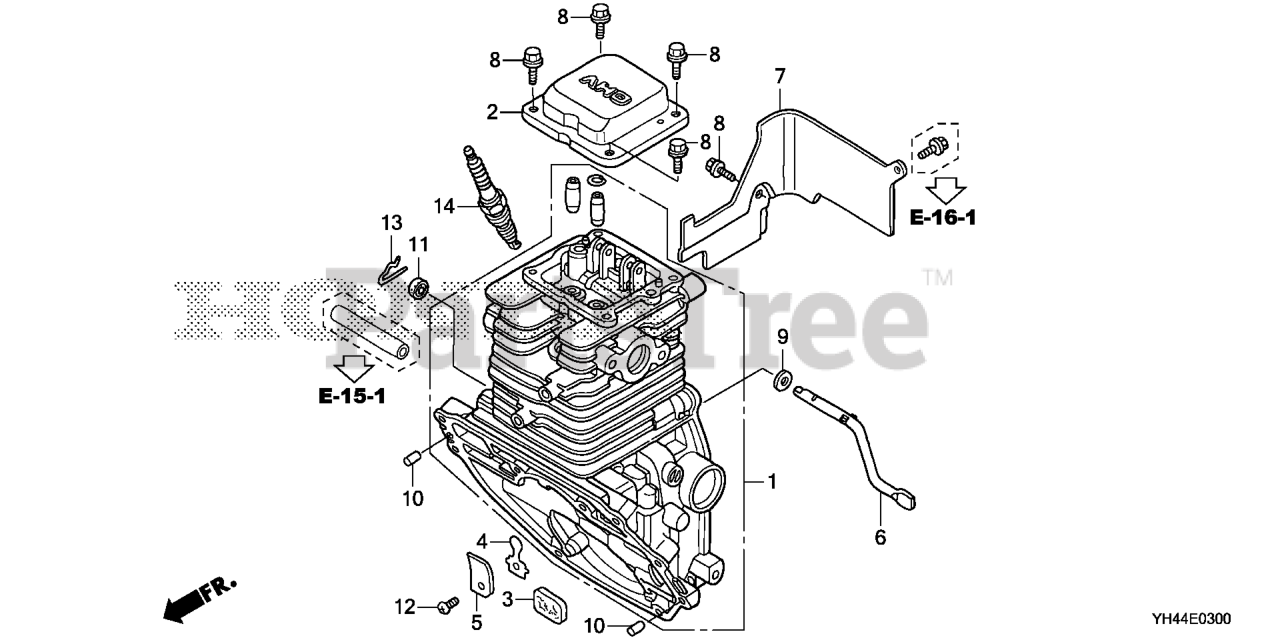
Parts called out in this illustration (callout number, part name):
2	COVER, HEAD
3	FILTER, BREATHER
4	VALVE, OIL OUTLET
5	PLATE, STOPPER
6	SHAFT, GOVERNOR ARM
8	BOLT, FLANGE (5X12)
9	WASHER (5.2X9)
10	ROLLER (6X14.8)
11	OIL SEAL (5X11X5)
12	SCREW, PAN (3X5)
13	PIN, LOCK (6MM)
14	SPARK PLUG (U14FSR-UB) (DENSO)
14	SPARK PLUG (CR4HSB) (NGK)
14	SPARK PLUG (U16FSR-UB) (DENSO)
14	SPARK PLUG (CR5HSB)
